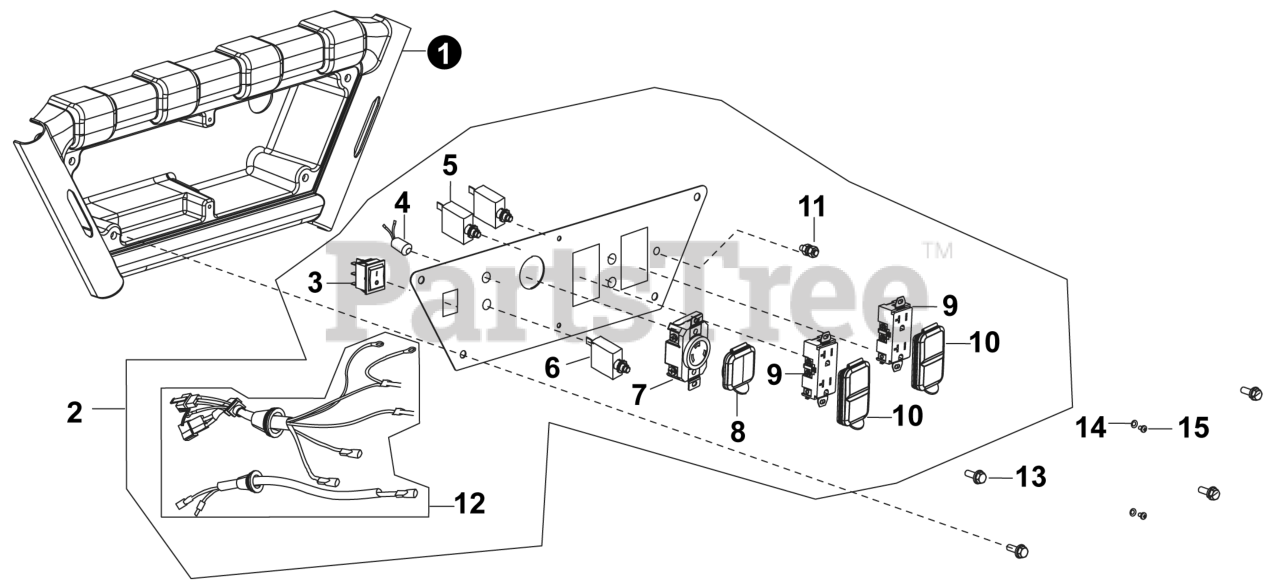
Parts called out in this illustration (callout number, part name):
1	SEAT, PANEL
2	PANEL, CONTROL
3	SWITCH, ON/OFF
4	LIGHT, LOW OIL INDICATOR
5	BREAKER, AC
6	BREAKER, AC
7	SOCKET, 120V TWISTLOCK
8	COVER, TWISTLOCK
9	SOCKET, 120V POWER
10	COVER, SOCKET
11	TERMINAL, GROUND BOLT
12	HARNESS SET, WIRING
14	WASHER, FLAT
